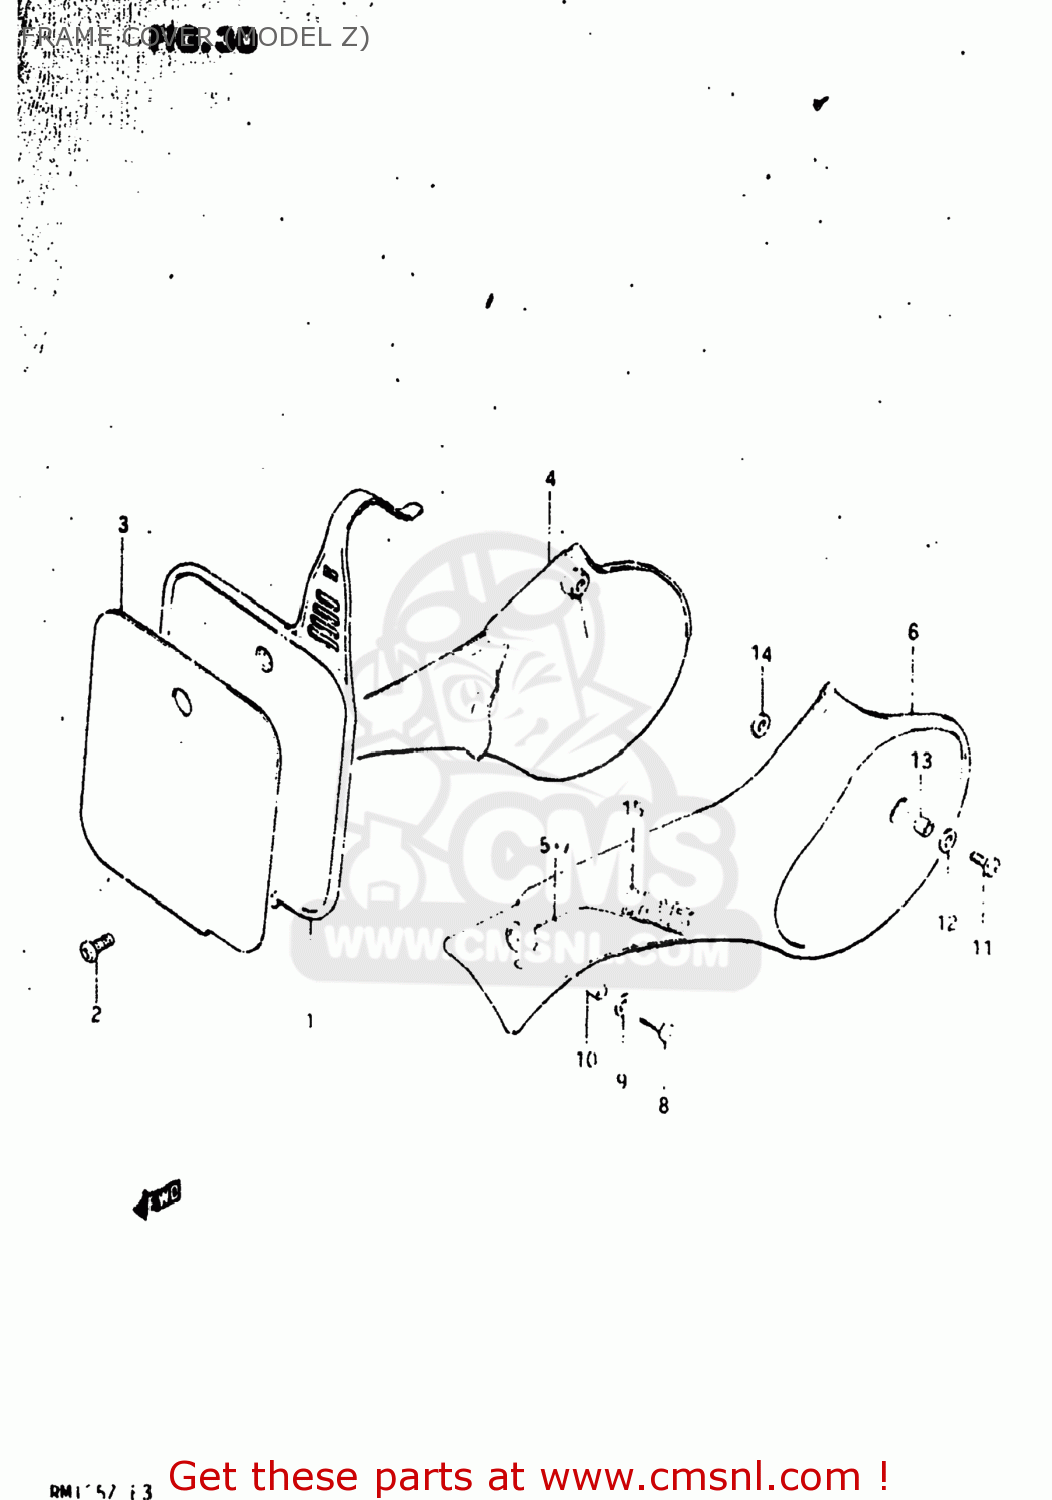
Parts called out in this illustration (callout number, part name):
1	PLATE,NUMBER,FRONT
2	SCREW
3	EMBLEM,FRONT NUMBER PLATE
4	COVER,FRAME,RIGHT
5	TAPE,FRAME COVER,RIGHT
6	COVER,FRAME,LEFT
7	TAPE,FRAME COVER,LEFT
8	SCREW(6X25)
9	WASHER FRAME COVER
10	SPACER,FRAME COVER,FRONT
11	SCREW
12	WASHER FRAME COVER
13	SPACER FRAME COV RR
14	GASKET
15	EMBLEM
